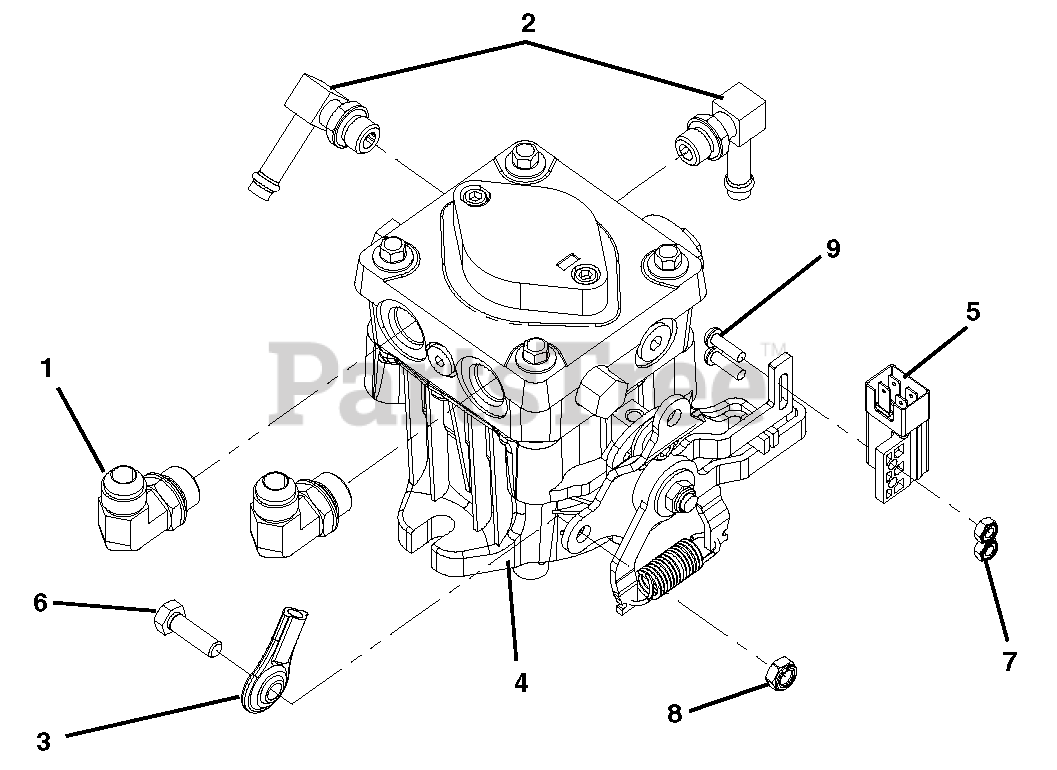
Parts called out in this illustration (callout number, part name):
1	Fitting, Includes O-Ring
2	Fitting - Adaptor .562-18 Steel Thread
3	Rod End, 5/16 RH
4	Pump, Left Hand Hydraulic PG-1KDA-D61X-XXXX
5	Switch, Plunger Diametral Pitch -N.O. -N.C.
6	Bolt, Hex .31 x 1.00 Grade 5
7	Nut, Locking, Nylon 10-24 w/Insert
8	Nut, Locking, Nylon .312-18
9	Screw, Machine 10-24 x .62 P/HD
